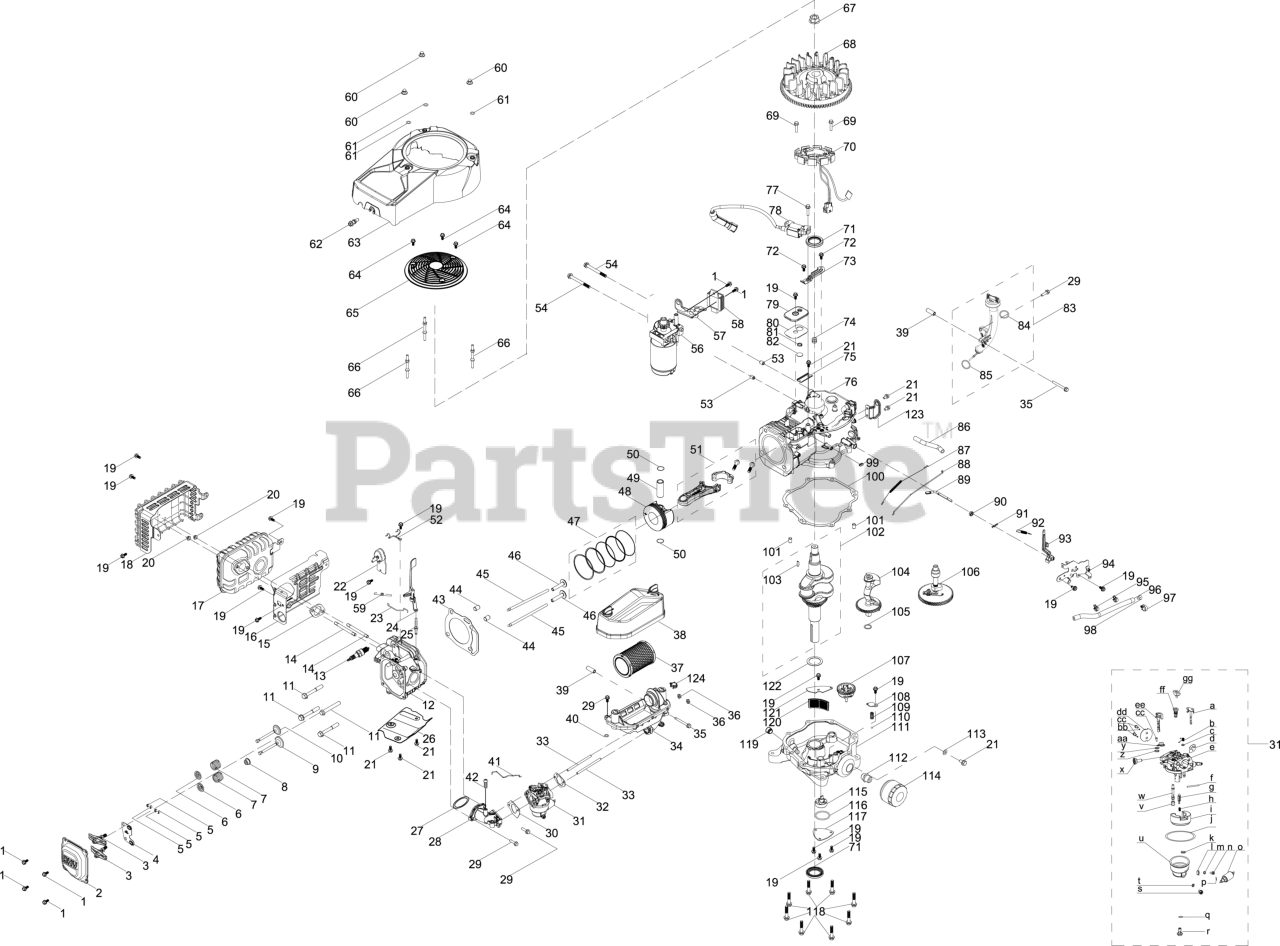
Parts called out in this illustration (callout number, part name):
1	BOLT M6 x 16
2	VALVE COVER
3	ROCKER ARM ASSEMBLY
4	ROCKER ARM BASE
5	VALVE CAP
6	VALVE SPRING SEAT
7	VALVE SPRING
8	INTAKE VALVE SEAL
9	INTAKE VALVE
10	EXHAUST VALVE
11	BOLT M10-1.25 x 70
12	CYLINDER HEAD
13	SPARK PLUG (F6RTC/RN11YC/BPR6ES)
14	STUD - M8 x 102
15	EXHAUST GASKET
16	ENGINE SHROUD
18	MUFFLER GUARD
19	BOLT M6-1 x 14 GR8.8
21	BOLT M6-1 x 12 GR8.8
22	THERMAL SWITCH
23	THERMAL LEVER
24	AIRVANE CHOKE
25	PIVOT VANE STUD
26	ENGINE SHROUD
27	O-RING 36 x 2.5
28	INTAKE MANIFOLD
29	BOLT M6 x 22
30	INTAKE GASKET
31	CARBURETOR ASSEMBLY HY-7T84JU
32	AIR FLTER GASKET
33	STUD M6-1.00 x 92
34	AIR FILTER BASE ASSEMBLY
35	SCREW M6-1:50:CL5.
37	AIR FILTER W/PREFILTER
38	AIR FILTER COVER ASSEMBLY
39	BUSHING - 11X6X30
40	CARB FUEL DRAIN GASKET
41	CHOKE LEVER
42	SELF TAPPING SCREW 4.8 x 16
43	CYLINDER HEAD GASKET
45	PUSH ROD - INDIVIDUAL
46	TAPPET
47	PISTON RING SET
49	PISTON PIN
50	PISTON PIN SNAP RING
51	CONNECTING ROD ASSEMBLY
54	BOLT M8-1.25 x 80
56	ELECTRIC STARTER ASSEMBLY
59	IDLE SPRING
60	ACORN NUT
63	ENGINE BLOWER HOUSING
64	BOLT M5 x 18
65	ENGINE SHROUD
66	STUD - M6 x 83
67	NUT M20 x 1.5
68	FLYWHEEL ASSEMBLY
69	BOLT M5 x 28
70	ALTERNATOR
71	OIL SEAL - 35X52X7
72	BOLT M5-.8 x 10
73	WIRE PLATE
75	BREATHER SCREEN
77	BOLT-M6-1 x 28 GR8.8
78	IGNITION COIL
79	BREATHER COVER
80	BREATHER COVER GASKET
81	BREATHER VALVE SPRING
82	BREATHER VALVE
83	DIPSTICK ASSEMBLY
86	BREATHER HOSE
87	THROTTLE DAMPENING SPRING
88	THROTTLE LINKAGE
89	GOVERNOR GEAR SHAFT
90	GOVERNOR SEAL
91	COTTER PIN
92	GOVERNOR SPRING
93	GOVERNOR ARM ASSEMBLY
94	CONTROL BRACKET ASSEMBLY
95	HOSE CLAMP
96	FUEL HOSE 6.3 x 12.5 x 250
97	FUEL LINE SUPPORT CLAMP
100	CRANKCASE GASKET
101	DOWEL PIN 9 X 14
102	CRANKSHAFT ASSEMBLY
103	WOODRUFF KEY
104	BALANCE SHAFT ASSEMBLY
105	WASHER 17.2 x 26 x 1
106	CAMSHAFT ASSEMBLY
107	GOVERNOR GEAR
108	PRESSURE RELEASE COVER
109	PRESSURE RELEASE SPRING
110	OIL PUMP STEEL BALL
111	CRANKCASE COVER
112	SCREW JOINT OIL FILTER ADAPTER
113	WASHER - 6.2X1.5X13
114	ENGINE OIL FILTER
115	OIL PUMP ASSEMBLY
117	OIL SEPARATOR
118	BOLT M8 x 40
119	ENGINE PLUG 3/8 NPT
120	FILTER SCREEN
121	OIL SCREEN PLATE
122	WASHER - 35.4X1X52
